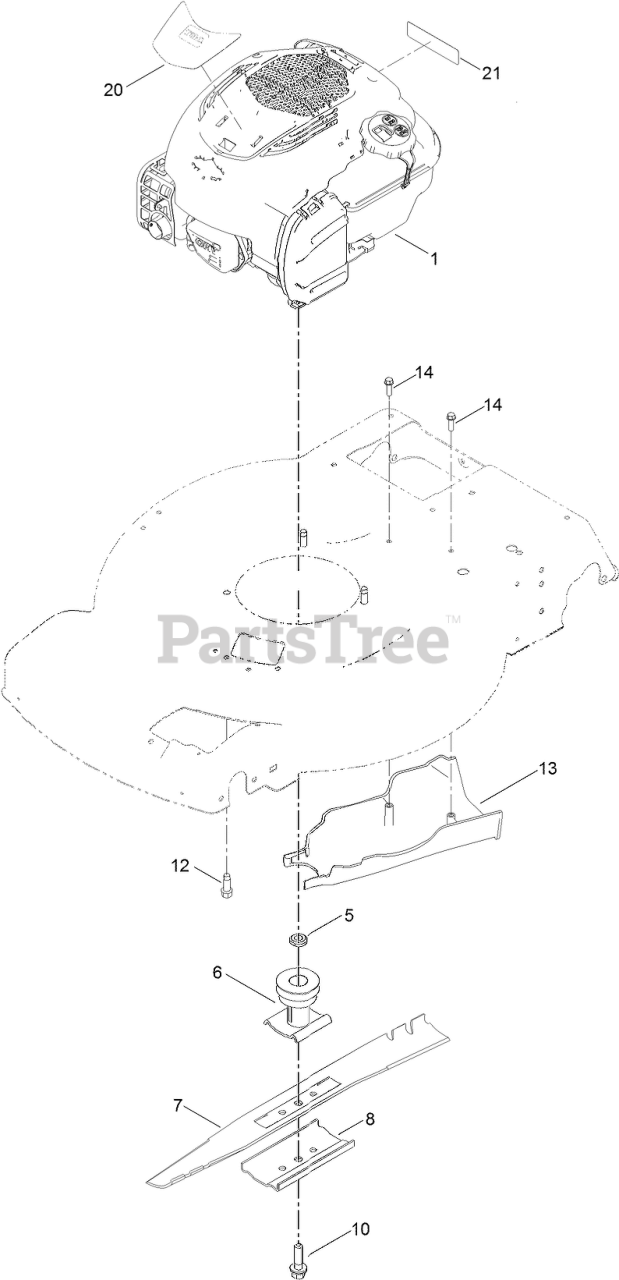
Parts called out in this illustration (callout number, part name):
5	SPACER-DRIVER
6	DRIVER-BLADE
7	BLADE-22 INCH
8	SUPPORT-BLADE
10	BOLT-BLADE
12	SCREW-TAPTITE
13	COVER-BELT, REAR
14	SCREW-HWH
20	DECAL-SHROUD, BRIGGS
21	DECAL-ARRESTOR, SPARK
